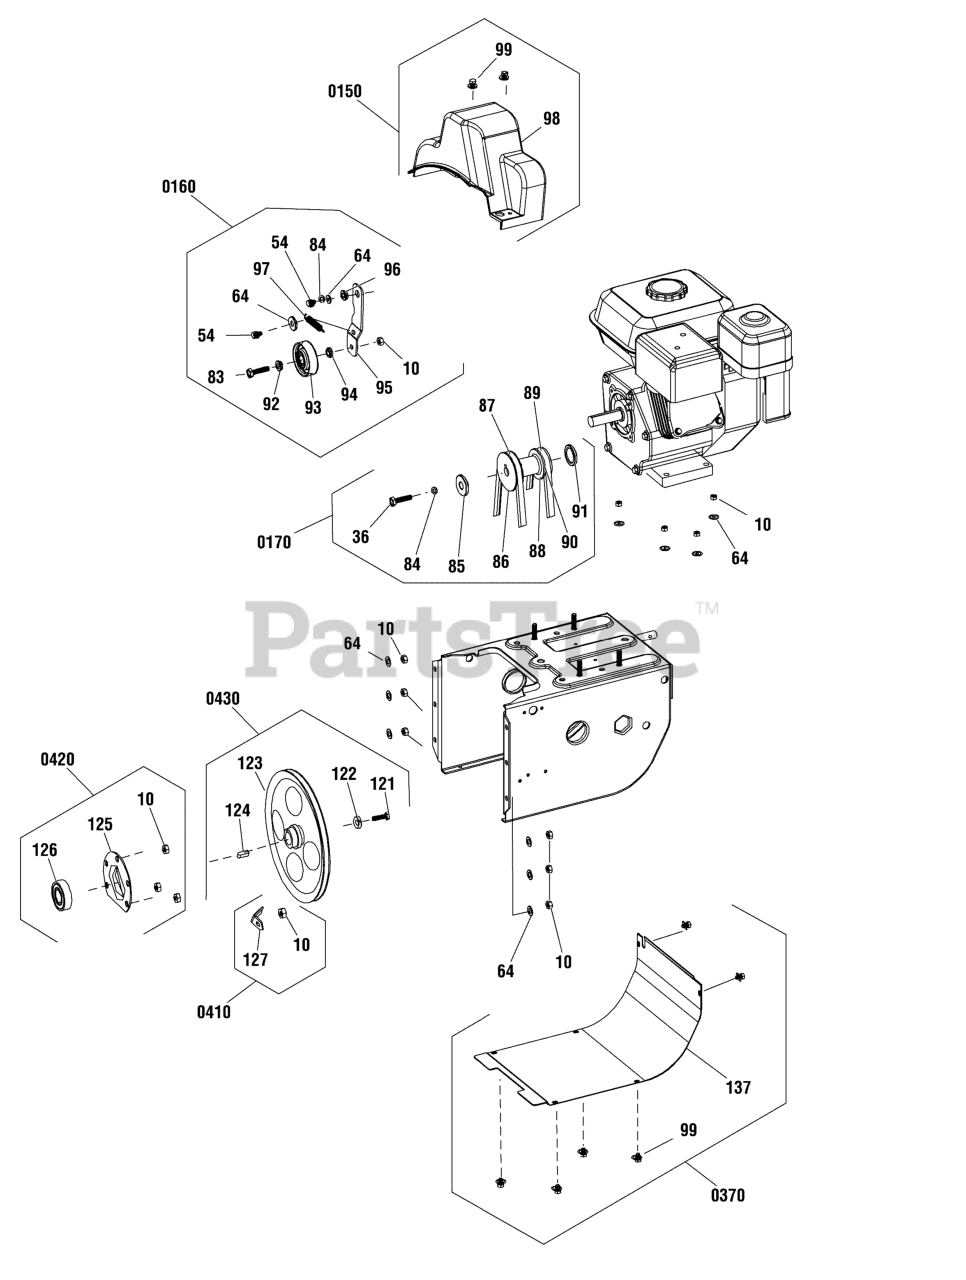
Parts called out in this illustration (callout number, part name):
10	*NUT, Lock, Hex Head, non-metal
36	*SCREW, Hex head
54	*SCREW, Hex head
64	*WASHER, Flat
83	*SCREW, Hex head
84	*WASHER, Spring
85	*WASHER, Flat
86	*PULLEY, Impeller drive
87	BELT, Auger Drive
88	*RING, Retainer, Synch-pulley
89	BELT, Traction Drive
90	*SYNCH-PULLEY
91	*SPACER
92	*WASHER
93	*ASSEMBLY, Small Tensioning wheel
94	*PAD, small tensioning wheel
95	*PLATE, Small Tensioning
96	*PAD, small tensioning plate
97	*SPRING
98	*COVER, Belt
99	*SCREW, Hex head
121	*SCREW, Hex head
122	*WASHER, Flat
123	*PULLEY, Driven
124	*KEY, Flat
125	*COVER, Round bottom
126	*BEARING, Ball
127	*BELT, Backup Bar
137	*COVER, Motor Box Lower
0150	KIT, BELT COVER
0160	KIT, IDLER PULLEY, TRACTION DRIVE
0170	KIT, ENGINE PULLEY
0370	KIT, BOTTOM COVER
0410	KIT, BELT GUIDE, AUGER
0420	KIT, BEARING HARDWARE, AUGER PULLEY
0430	KIT, AUGER PULLEY
